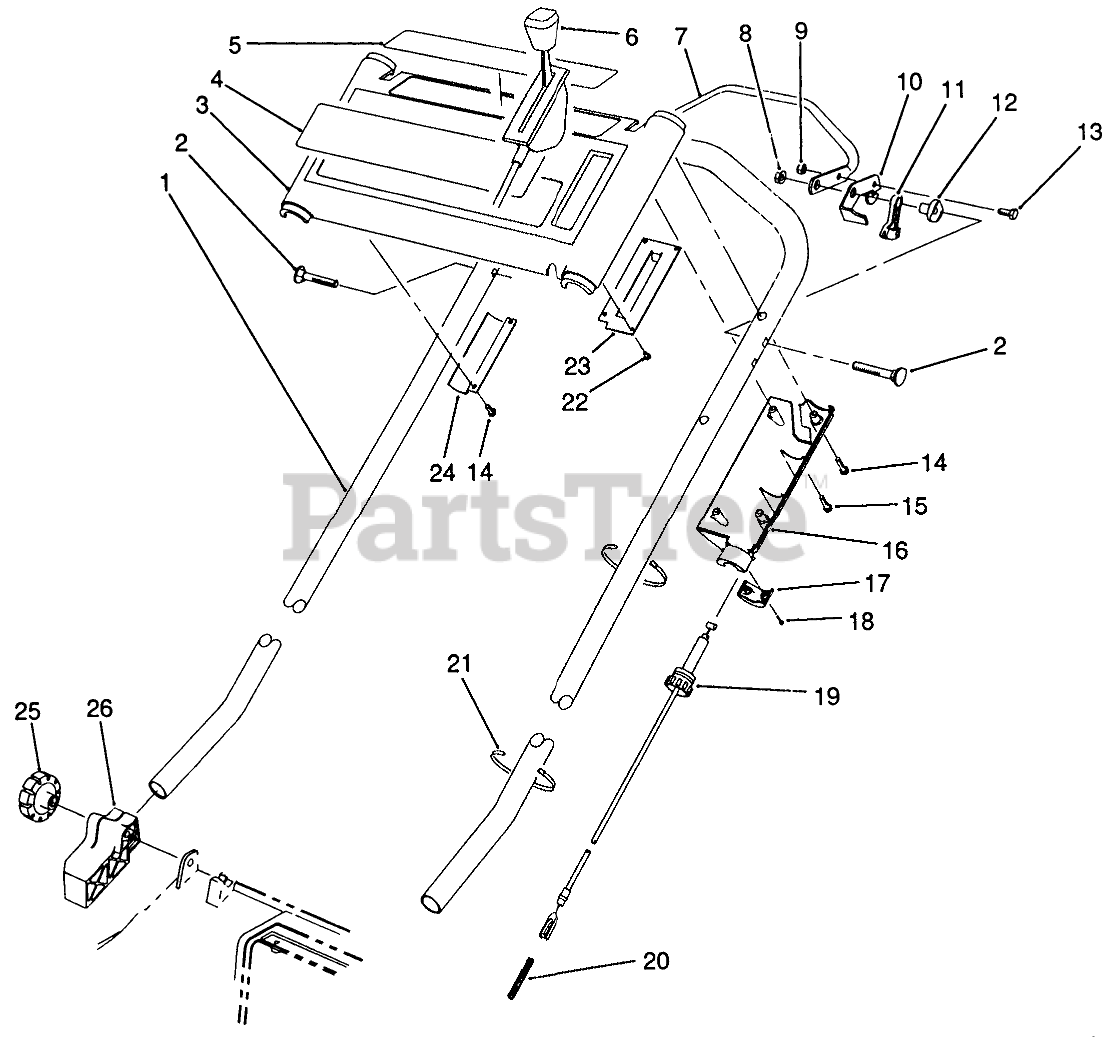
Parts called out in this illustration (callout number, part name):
1	Handle
2	SCREW-HANDLE
3	CONTROL PANEL W/DECAL
4	DECAL - TORO
5	DECAL - PANEL DANGER
6	THROTTLE CONTROL
7	CONTROL BAR
8	NUT-LOCK, NI
9	NUT-LOCK, NI
10	CONTROL LEVER
11	LEVER-TRACTION
12	SPACER-SUPPORT
13	SCREW-HH
14	SCREW-PPH, PLASTITE
15	Screw
16	Cover-Throttle Lower
17	LOWER THROTTLE CAP
18	#4-14X.62 PLASTITE SCW
19	TRACTION CABLE
20	SPRING-COMPRESSION
21	TIE-CABLE
22	#6-19X.25 PLASK FORM SC
23	THROTTLE PLATE
24	Bracket-Panel
26	MOUNT-HANDLE, RH
